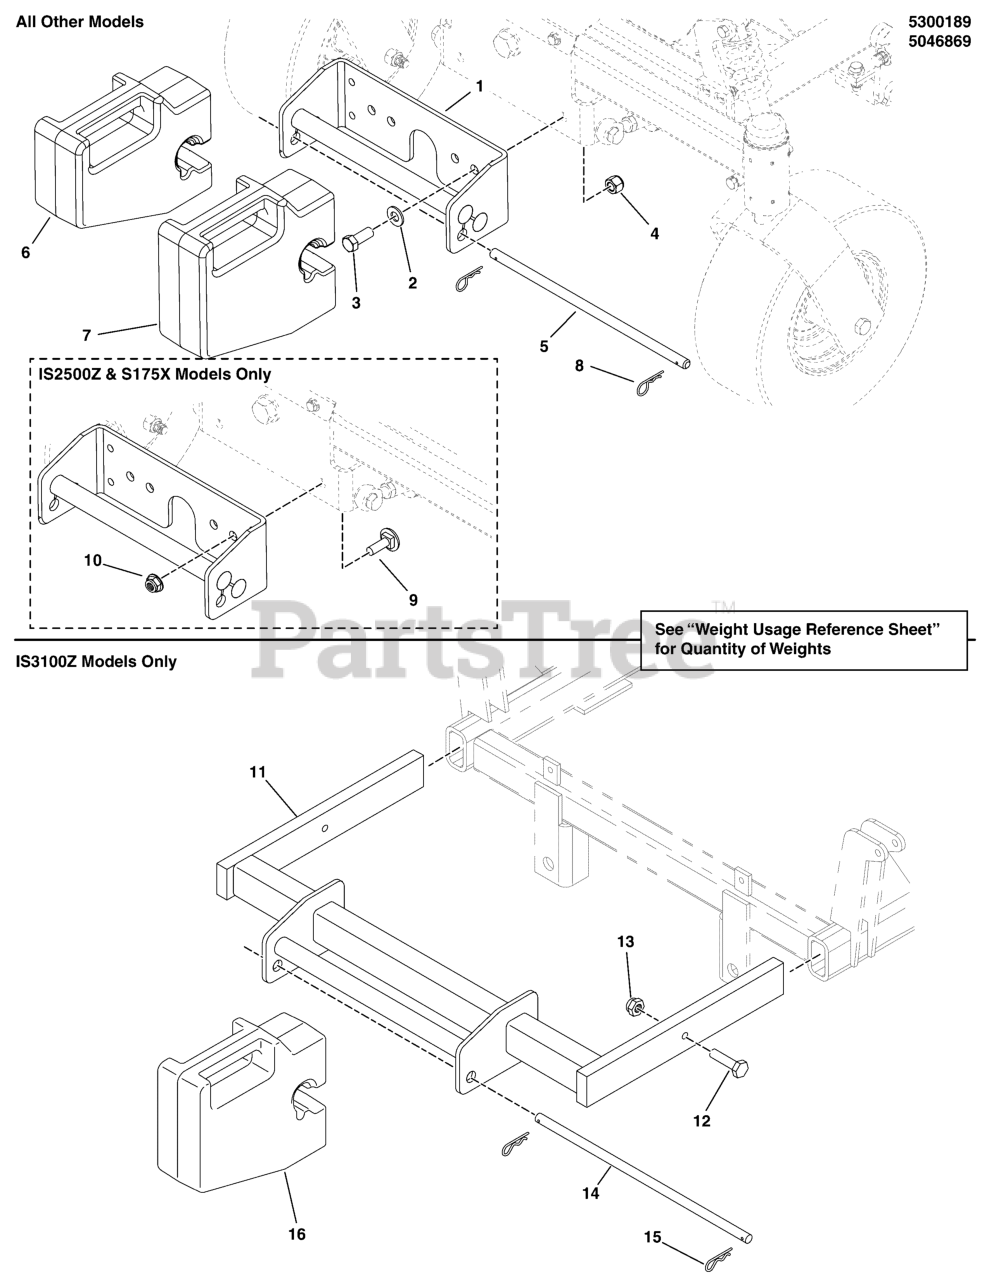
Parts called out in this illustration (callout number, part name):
1	HOLDER ASMY-WEIGHT CONS Z CAT - BLACK
2	WASHER, 1/2 SAE
3	BOLT, 1/2-20 X 1-1/4" GD5 CZ
4	NUT, Hex, Nylon Lock, 1/2-20
5	ROD-.500DIA 13.75LG YELLOW CON
6	WEIGHT-QUICK ATTACH 33LBS PAINTED BLACK
7	WEIGHT-QUICK ATTACH 50LB SUITCASE PAINTED
8	3/32 X 1-5/8 HAIR PIN CLIP
9	BOLT, CARRIAGE 1/2-13 X 1-1/4 GD.5
10	NUT, Hex Flange, Nylock, 1/2-13
11	3-BAG WEIGHT RACK WELDMENT
12	HHCS, 3/8-16 X 2.00, GR5, ZINC/CLEAR
13	NUT, Hex, Nylon Locking, 3/8-16
14	ROD, WEIGHT RETAINER
15	3/32 X 1-5/8 HAIR PIN CLIP
16	WEIGHT-QUICK ATTACH 50LB SUITCASE PAINTED
